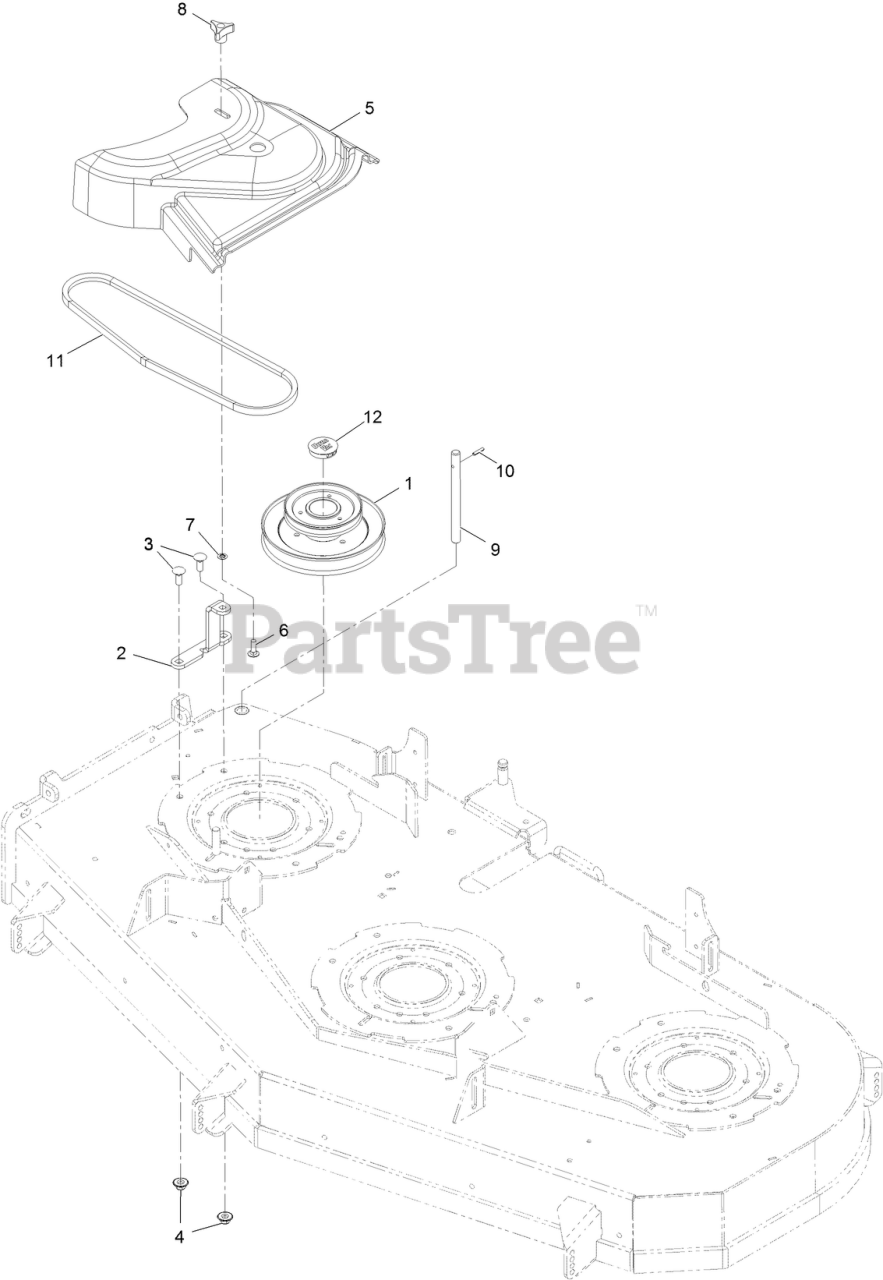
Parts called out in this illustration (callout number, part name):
1	JACKSHAFT,UV DRIVE 604 SPLINED
2	BRACKET-BELT COVER
3	BOLT-CARR
4	Nut-Nyloc 3/8-16 Flg
5	COVER-BELT, UV 60 ENTRY
6	BOLT-CARR
7	RING-RETAINING, BOLT
8	KNOB-3 PRONG
9	SHAFT-CATCHER, GRASS
10	PIN-ROLL
11	V-BELT (17569)
12	PLUG, BLACK NYLON 1.75
